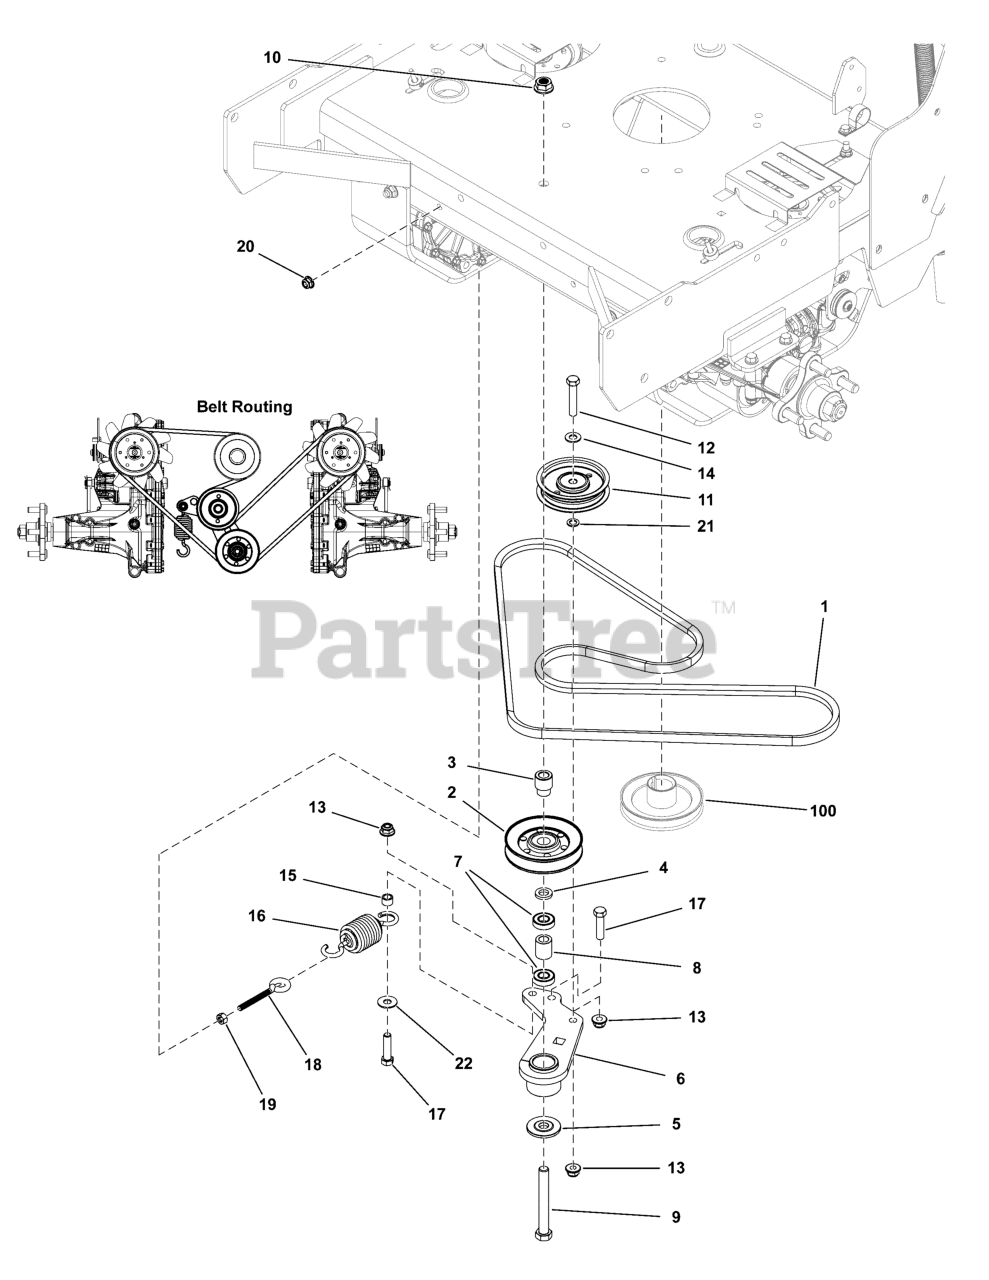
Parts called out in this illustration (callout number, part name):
1	BELT, A-SEC, COG TYPE, 76.2" EL ARAMID
2	PULLEY-IDLER-V, 4.00OB, .669ID, .88W,STL
3	INSERT, BEARING, .51ID X .90OD X 1.15L
4	SPACER, .52 X .88 X .14, HT
5	SPACER, IDLER ARM, 1/2, PM
6	WELD, IDLER, HYDRO, W45 - BLK
7	BEARING, BALL, AXLE
8	SPACER, .52 X .84 X 1.00, PM
9	BOLT, 1/2-13 X 4" GD5 CZ
10	NUT, Hex Flange, Nylock, 1/2-13
11	PULLEY, FLAT IDLER, 3-1/4" FLANGED
12	HHCS, 3/8-16 X 2.00, GR5, ZINC/CLEAR
13	NUT, 3/8 - 16 HEX NYLOCK FLANGE
14	WASHER, 3/8 SAE
15	SPACER, .39 X .55 X .38, PM, CZ
16	SPRING EXT, 1.50ODX4.75LGX.177WR, BLK
17	BOLT, 3/8-16 X 1-3/4" GD5 CZ
18	EYE BOLT,5/16-18 X3.5,2.13THRD,.55EYE,CZ
19	NUT, 5/16-18 HEX
20	NUT, 5/16-18 HEX NYLOCK FLANGE NUT
21	SPACER, .385"ID X .625" OD X .062" THK
22	WASHER, 3/8" USS
100	Refer to: Engine & PTO Group
